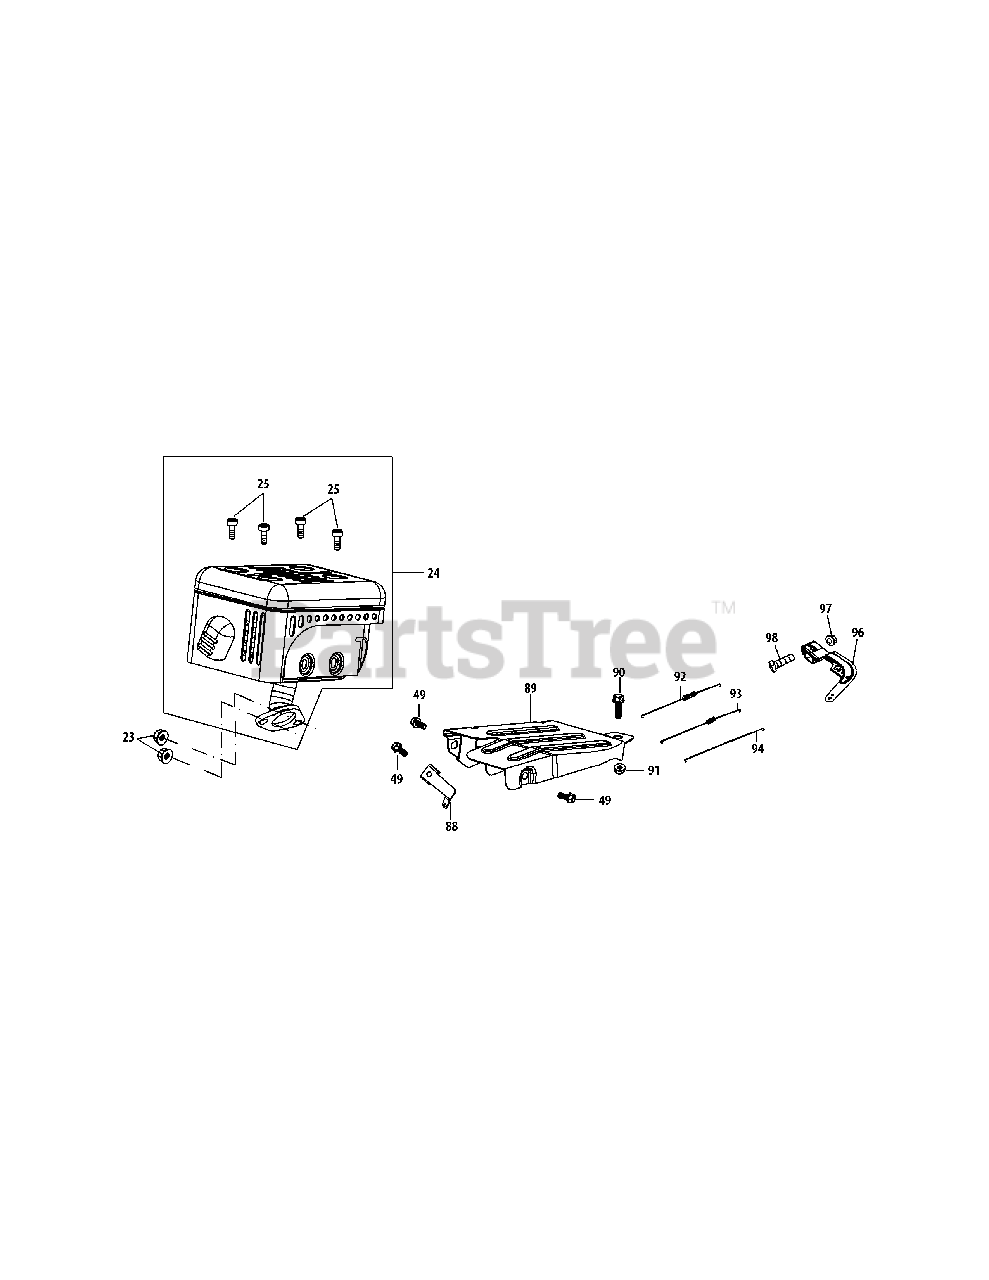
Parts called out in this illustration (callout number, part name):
24	Muffler Assembly
25	Bolt M5×10
49	Bolt M6×12
88	Covernor Spring Bracket
89	Governor Shield
90	Bolt M6×28
91	Nut M6
92	Governor Spring
93	Throttle Return Spring
94	Governor Rod
96	Governor Arm
97	Nut M6
98	Governor Arm Bolt
